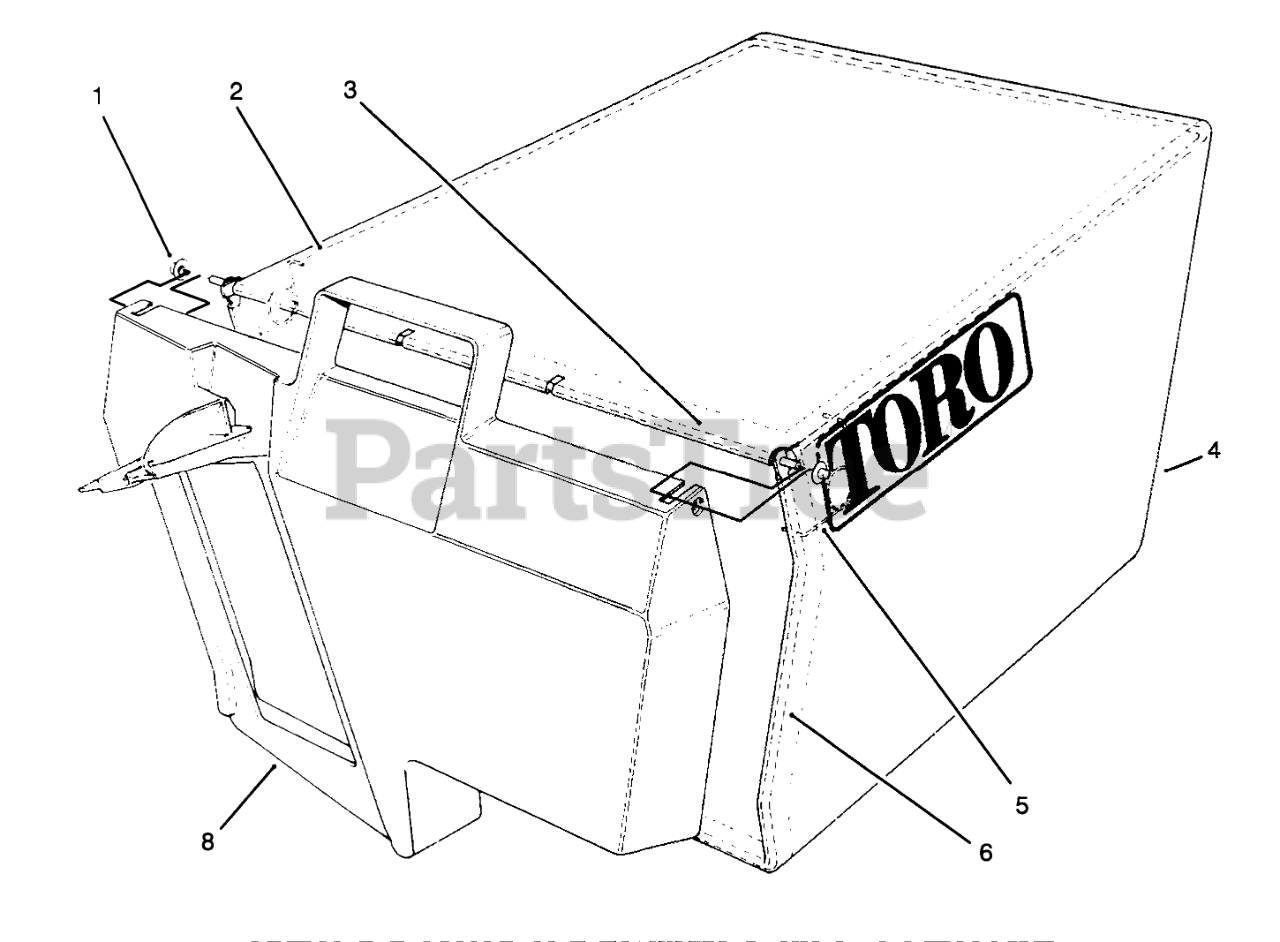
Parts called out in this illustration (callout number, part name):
1	NUT-PUSH
2	FRAME-BAG, UPPER
3	HINGE-DOOR, BAG
4	Bag
5	SPRING
6	FRAME-BAG
8	DOOR-BAG
